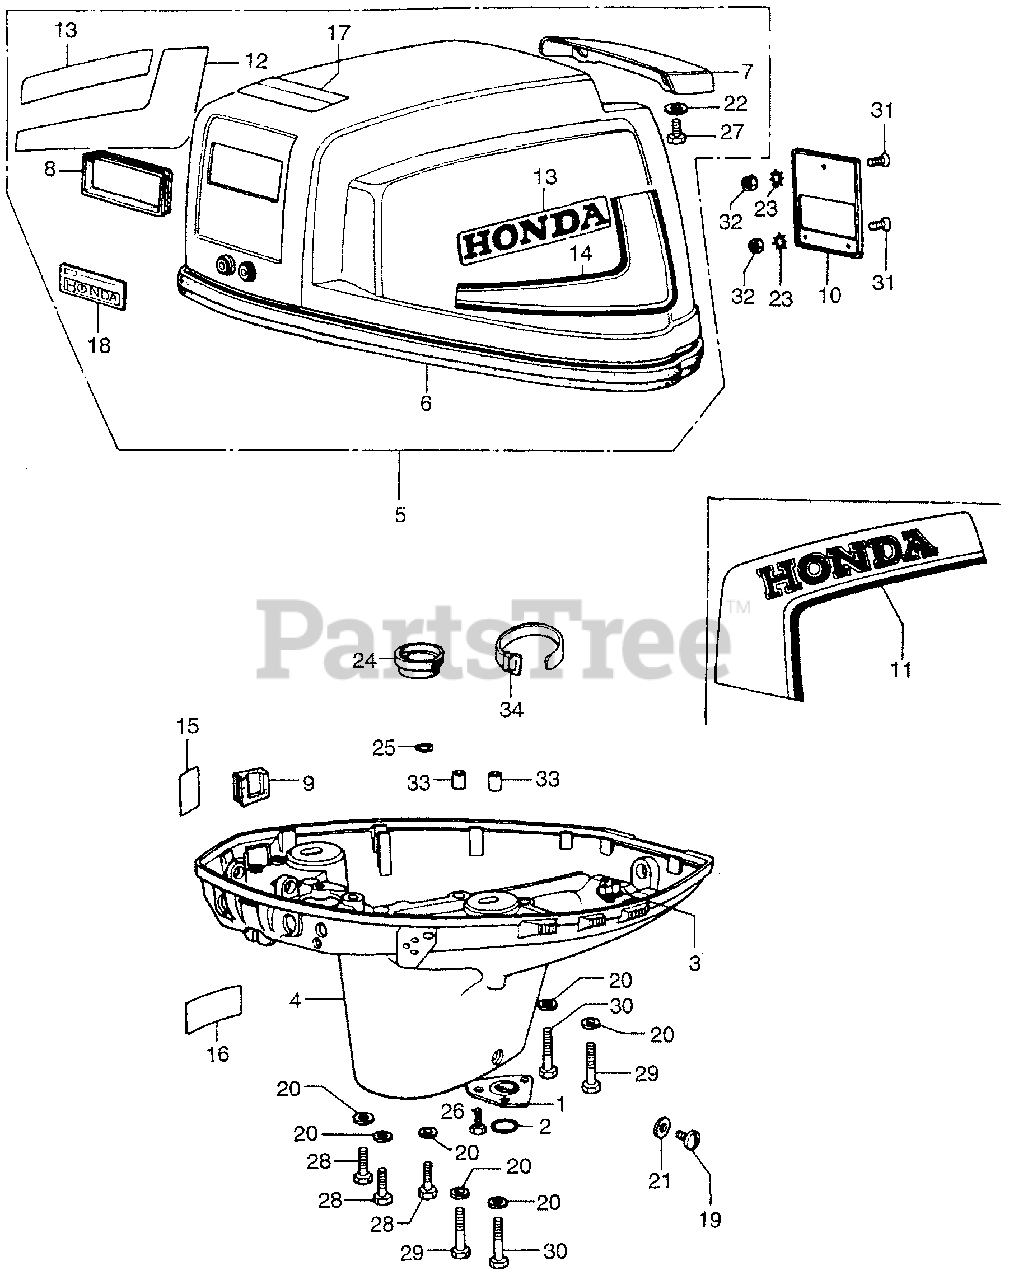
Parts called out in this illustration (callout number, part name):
1	PLATE, EX.
3	MANIFOLD, TUBE
4	CASE, OIL *PB1* (DARK BLUE)
5	COVER, ENGINE *PB52/NH31* (AQUARIUS BLUE/MC KINLEY WHITE) (N/A: SEE COMPONENTS)
6	SEAL, ENGINE COVER
7	HANDLE, TILT *PB1* (DARK BLUE)
8	SEAL, RECOIL (NOT AVAILABLE)
9	GROMMET A, OIL CASE (NOT AVAILABLE)
10	EMBLEM, RR. (NOT AVAILABLE)
12	EMBLEM, R. SIDE COVER *PB52* (AQUARIUS BLUE)
13	LABEL, SIDE COVER (NOT AVAILABLE)
14	EMBLEM, L. SIDE COVER *PB52* (AQUARIUS BLUE) (NOT AVAILABLE)
15	MARK, CHANGE
16	LABEL, OIL FILLER POSITION
17	MARK, STARTER CAUTION
19	BOLT, OIL CHECK
20	WASHER, PLAIN (6MM)
21	WASHER C (8MM)
22	WASHER (6MM)
23	WASHER, LOCK (4MM) (NOT AVAILABLE)
24	SEAL, COUPLING (NOT AVAILABLE)
25	O-RING (9.8X1.9)
26	BOLT, HEX. (5X10)
27	BOLT, HEX. (6X16)
28	BOLT, HEX. (6X32) (NOT AVAILABLE)
29	BOLT, HEX. (6X35)
30	BOLT, HEX. (6X45)
31	SCREW, PAN (4X8)
32	NUT, HEX. (4MM)
33	PIN A, DOWEL (8X14)
34	BAND B1, CABLE
